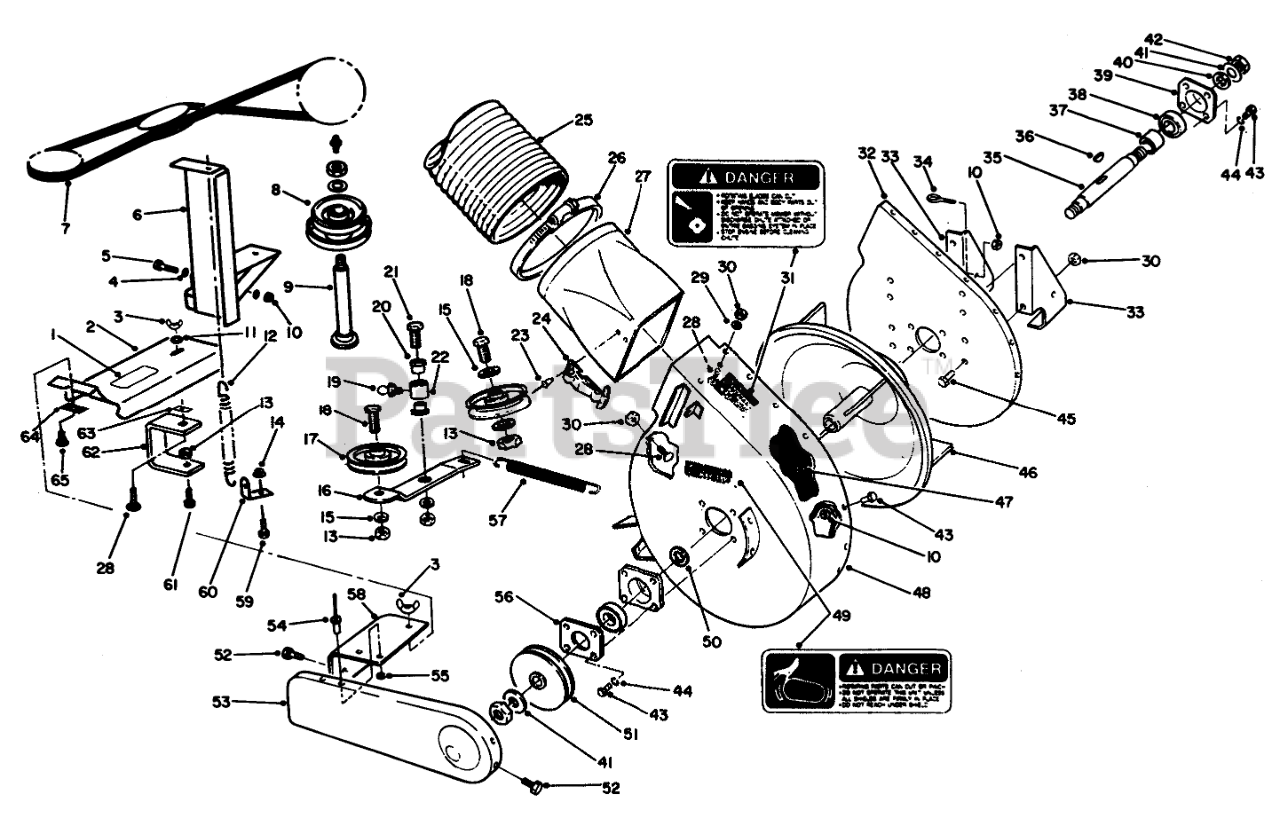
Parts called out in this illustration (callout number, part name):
1	DECAL-DANGER
2	COVER-BELT B
3	NUT-WING, LOCK
4	WASHER-FLAT
5	Bolt
6	SUPPORT-SPRING W. B
7	BELT-V
8	PULLEY-BLOWER DR
9	SHAFT-SPINDLE
10	NUT-LOCK, NI
11	WASHER-FLAT
12	SPRING-EXTENSION
13	NUT-LOCK, NI
14	NUT-HF
15	WASHER-FLAT
16	ARM-IDLER-WELDED B
17	Pulley-Idler
18	SCREW-HH
19	FITTING-GREASE
20	BUSHING
21	SCREW-HH
22	SPACER
23	RIVET
24	HANDLE ASM
25	HOSE 6" X 48"
26	CLAMP
27	ADAPTER
28	BOLT-CARR
29	WASHER-PLAIN
30	NUT-LOCK, NI
31	DECAL-DANGER
32	BLOWER MTG PLATE W A B
33	BRACKET-BLOWER MT B
34	EYE BOLT
35	SHAFT- BLOWER
37	SPACER
38	BEARING-BALL
39	CUP-BEARING
40	Washer
41	WASHER-SPECIAL
42	NUT 5/8-11 L.H.
43	SCREW-HH
44	WASHER-LOCK
45	SCREW-HH
46	IMPELLER - WELDED BLACK
47	STRIP-WEAR
48	Housing-Blower
49	DECAL-DANGER
50	SPACER-BEARING
51	PULLEY-BLOWER R
52	Bolt
53	SHIELD
54	RIVET-BLIND
55	Washer
56	Cover-Plate
57	SPRING
58	SHIELD-PULLEY B
59	SCREW-HH
60	CLIP - SPRING
61	SCREW-HH
62	BRACKET-SHIELD B
63	NUT 5/16-18 FLAT
64	STRAP B
65	SCREW-CARR
